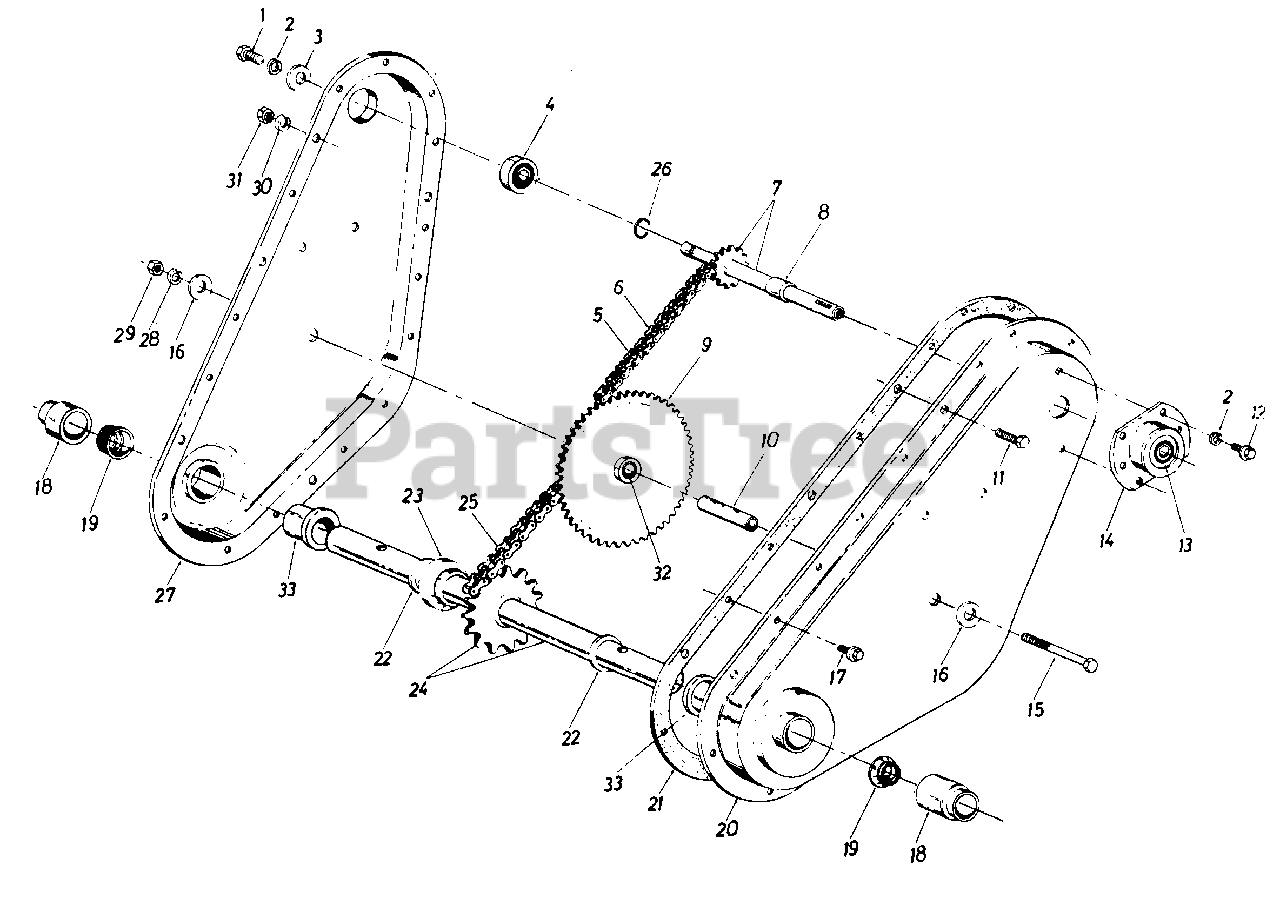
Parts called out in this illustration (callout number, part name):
1	Hex L-Scr. 1/4-28 x .625" Lg.
2	L-Wash. 1/4" I.D.*
3	Fl-Wash. .25" I.D. x .93" O.D. x .125" Thk.
4	Bearing .62" I.D. x 1.38" O.D. x .437" Thk.
5	#35 Chain 3/8" Pitch x 52 Links Endless
6	Master Link
7	Input Shaft Assembly
8	Spacer
9	Sprocket Assembly
10	Sprocket Hub Tubing 3/8" I.D. x 5/8" O.D. x 1.9" Lg.
11	Hex Scr. 5/16-18 x .625" Lg.*
12	Hex Wash. Hd. Self-Tap Scr. 1/4-20 X .50' Lg.
13	Bearing .625" I.D. x 1.38" O.D. x .437" Thk.
14	Bearing Housing
15	Hex Scr. 3/8-24 x 2.75" Lg.
16	Fl-Wash 3/8" I.D. x 1.25"
17	Hex Wash. Hd. Self-Tap Scr. 1/4-20 x .50" Lg.
18	Dust Cap
19	Seal
22	Thrust Wash. 1.00" I.D. x .030" Thk.
23	Step Spacer
24	Tine Shaft Assembly
25	#50 Chain 5/8" Pitch x 46 Links Endless
26	Snap Ring
29	Hex Nut 3/8-24 Thd.
30	L-Wash. 5/16" Scr.*
31	Hex Nut 5/16-18 Thd.*
32	Bearing
33	Bearing
